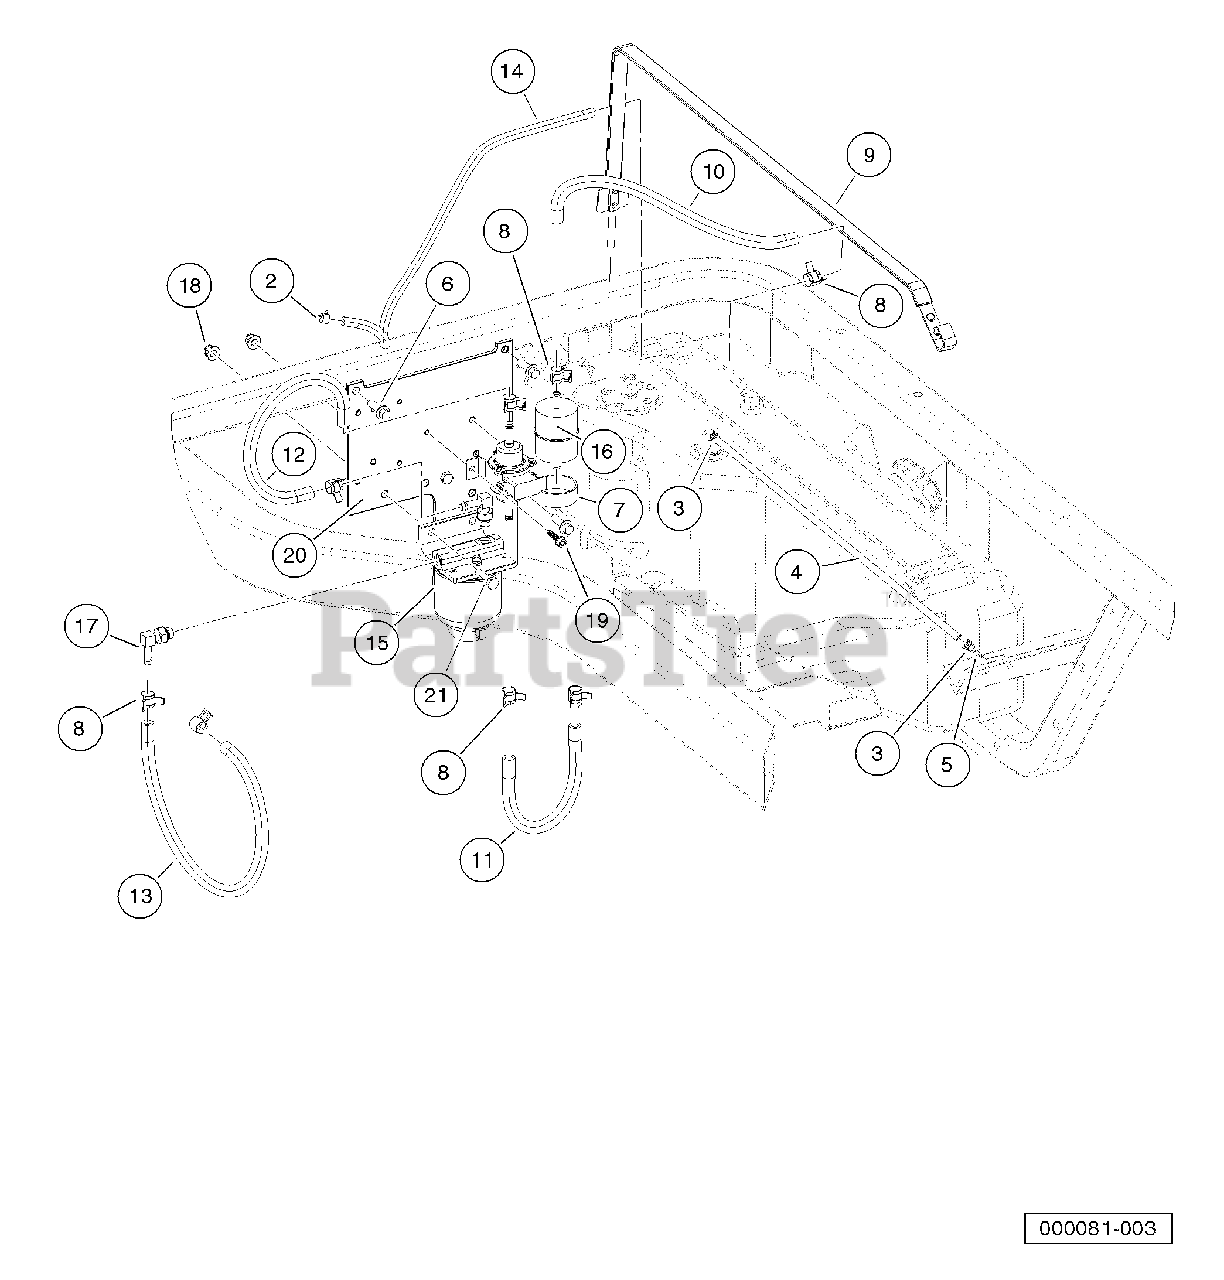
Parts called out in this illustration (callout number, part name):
1	Asm, Fuel System, Kubota
2	Clamp, Green Hose
3	Clamp, 0.301 ID Hose
4	Hose, Fuel, Vent, 22" Long
6	Screw, M8X1.25X30, Hex
7	P-Clamp, Insulated 1.75 In
8	Clamp, Hose, Ctb 14mm
9	Strap, Tank, Fuel
10	Hose, Tank To Prefilter Diesel
11	Hose, Fuel Prefilter To Pump
12	Hose, Fuel Pump To Filter
13	Hose, Fuel Filter To Eng
14	Hose, Fuel Return
15	Filter Assy, Fuel
16	Filter, Fuel
17	Adapter, 90, 5/16 Tube
18	Lock Nut, Flg M8 X 1.25 Nylon
19	Screw, M6 X 1 X 25 Thd Form
20	Plate, Fuel/Oil System
21	Bolt, M8 X 1.25 X 30
